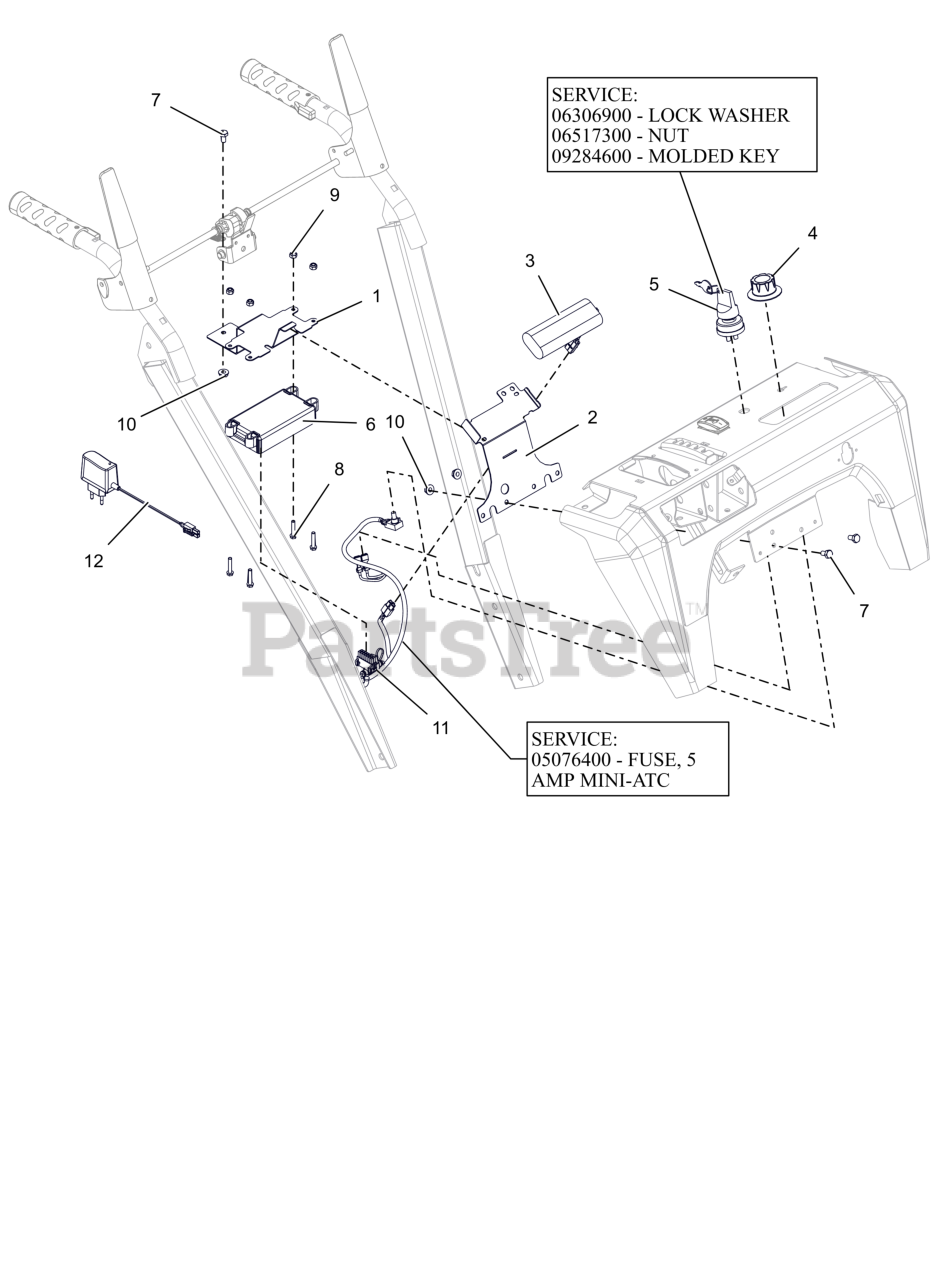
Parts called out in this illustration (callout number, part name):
1	BRACKET, ENGINE EFI-LCT LOWER
2	BRACKET, ENGINE EFI-LCT UPPER
3	BATTERY, SNOW EFI - 7.2V
4	KNOB, CONTROL - 2.063 ID
5	IGNITION SWITCH ASM - 2 POS
5	WSHR-LK-INT .625X.045 YWZC
5	NUT-PANEL .625-32 GRECO
5	KEY W/ SHIELD
6	ECU SERVICE LCT/CSI - 420CC
7	BLT,HEX .25-20X.50 G5 ZCC
8	BLT, HWH #10-24X1.00 ZCC
9	NUT-LK-NYL #10-24 G2 ZCC
10	NUT-LK-TOP-FLG .250-20 GF ZCC
11	HARNESS,WIRE - EFI ECU
11	FUSE, 5 AMP MINI-ATC
12	CHARGER, BATTERY-EFI 7.2V (EU)
